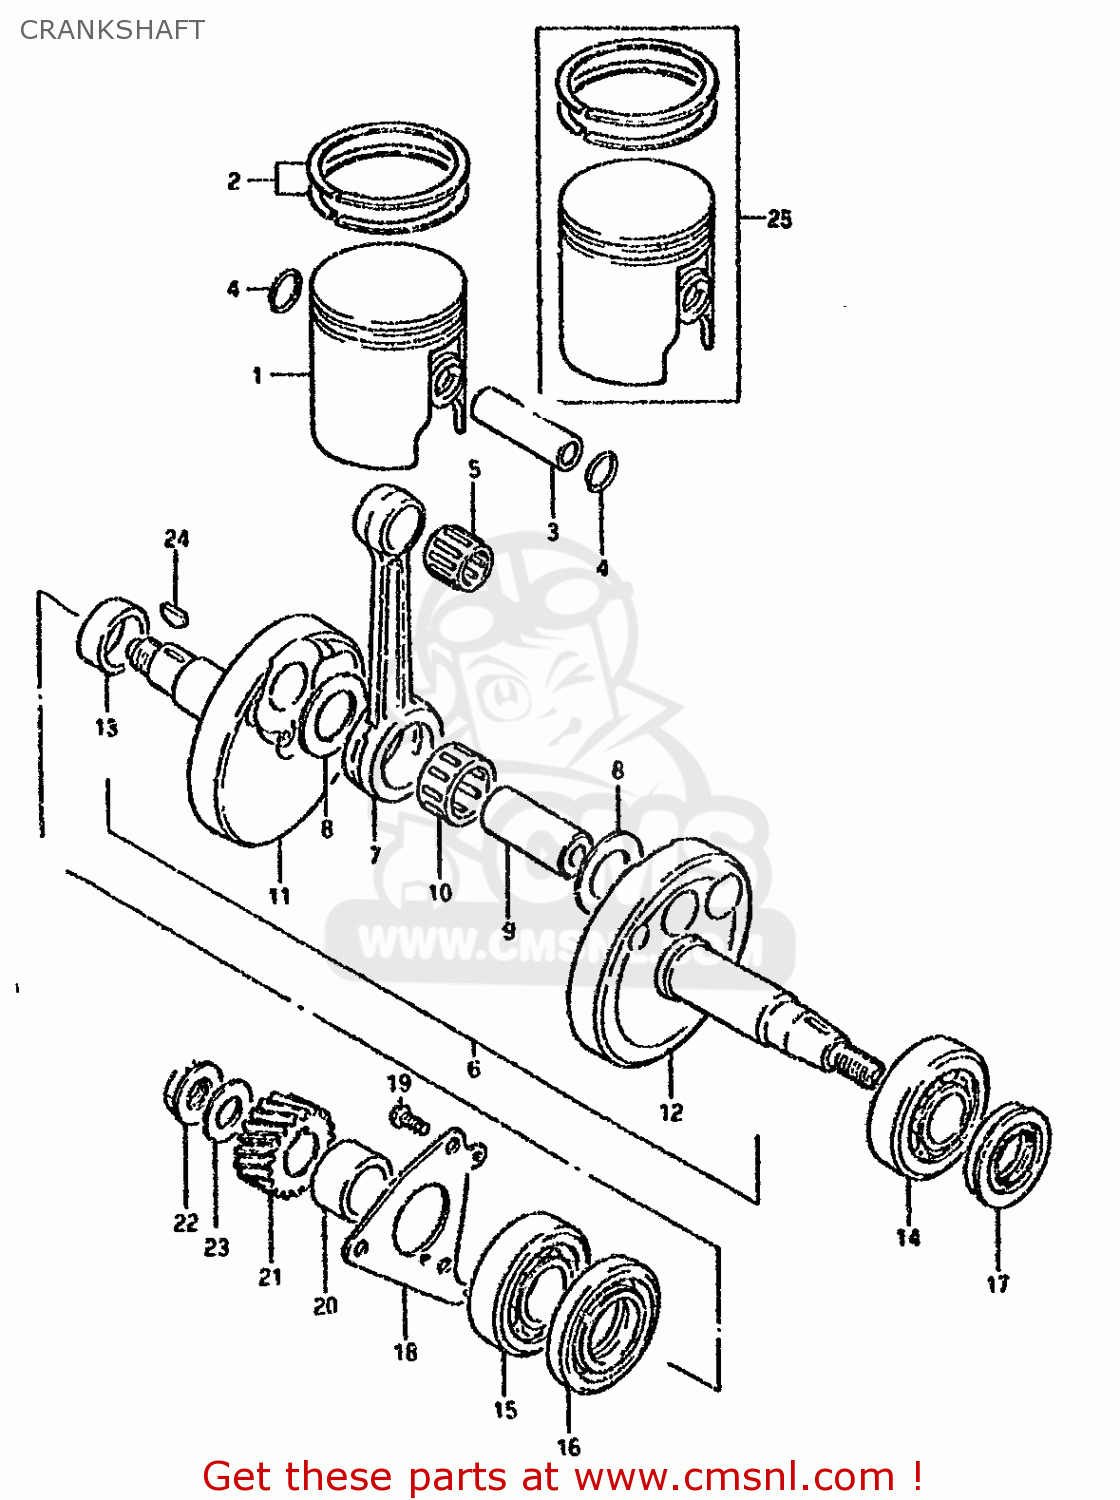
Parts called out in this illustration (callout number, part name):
1	PISTON (49.00MM)
2	PISTON RING SET STD
3	PIN,PISTON
4	RING,SNAP
5	ROLLER BEARING (12X16X1
6	CRANKSHAFT ASSY
7	ROD,CONNECTING
8	WASHER(17X29X1)
9	PIN,CRANK
10	BEARING(17X23X14)
11	CRANKSHAFT,RIGHT
12	CRANKSHAFT,L
13	SPACER(20X26X9)
14	BEARING(20X47X14)
15	BEARING(20X47X14)
16	SEAL,OIL(26X47X7.3)
17	SEAL,OIL(19.6X37X8)
18	RETAINER,CRANKSHAFT BEARING,R
19	SCREW
20	SPACER(20X26X14)
21	GEAR,PRIMARY DRIVE NO.19
22	NUT
23	WASHER
24	KEY
25	PISTON SET (OS:0.5)
